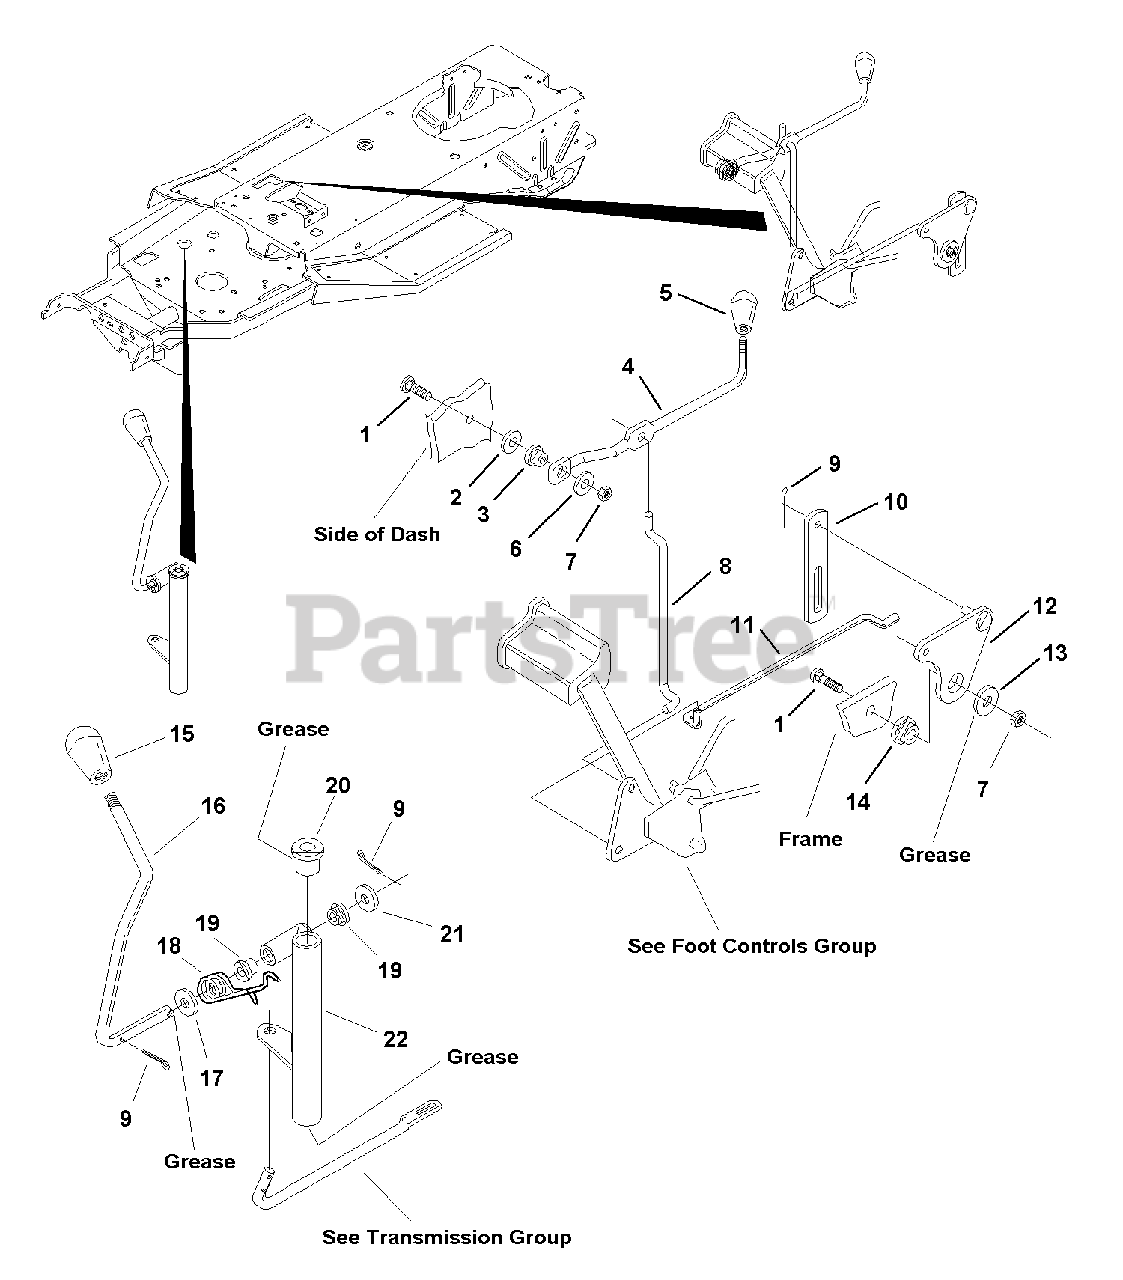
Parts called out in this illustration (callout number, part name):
1	CARRIAGE BOLT, 5/16-18 x 1-1/4
2	WASHER, 3/8
4	ROD, Lift Handle
5	KNOB, Lift Rod
6	WASHER, 5/16
7	LOCKNUT, Hex, 5/16-18
8	ROD, Lift, Upper
9	PIN, Cotter
10	LINK, Lift, Upper
11	ROD, Link, Lift
12	CAM & WELD PIN ASSEMBLY, Lift
13	WASHER, 5/16
14	SPACER
16	ROD, Shift
17	WASHER, 1/2
20	BUSHING
21	WASHER, 1/2
22	LEVER, Tube & Pivot Assembly, Shift
